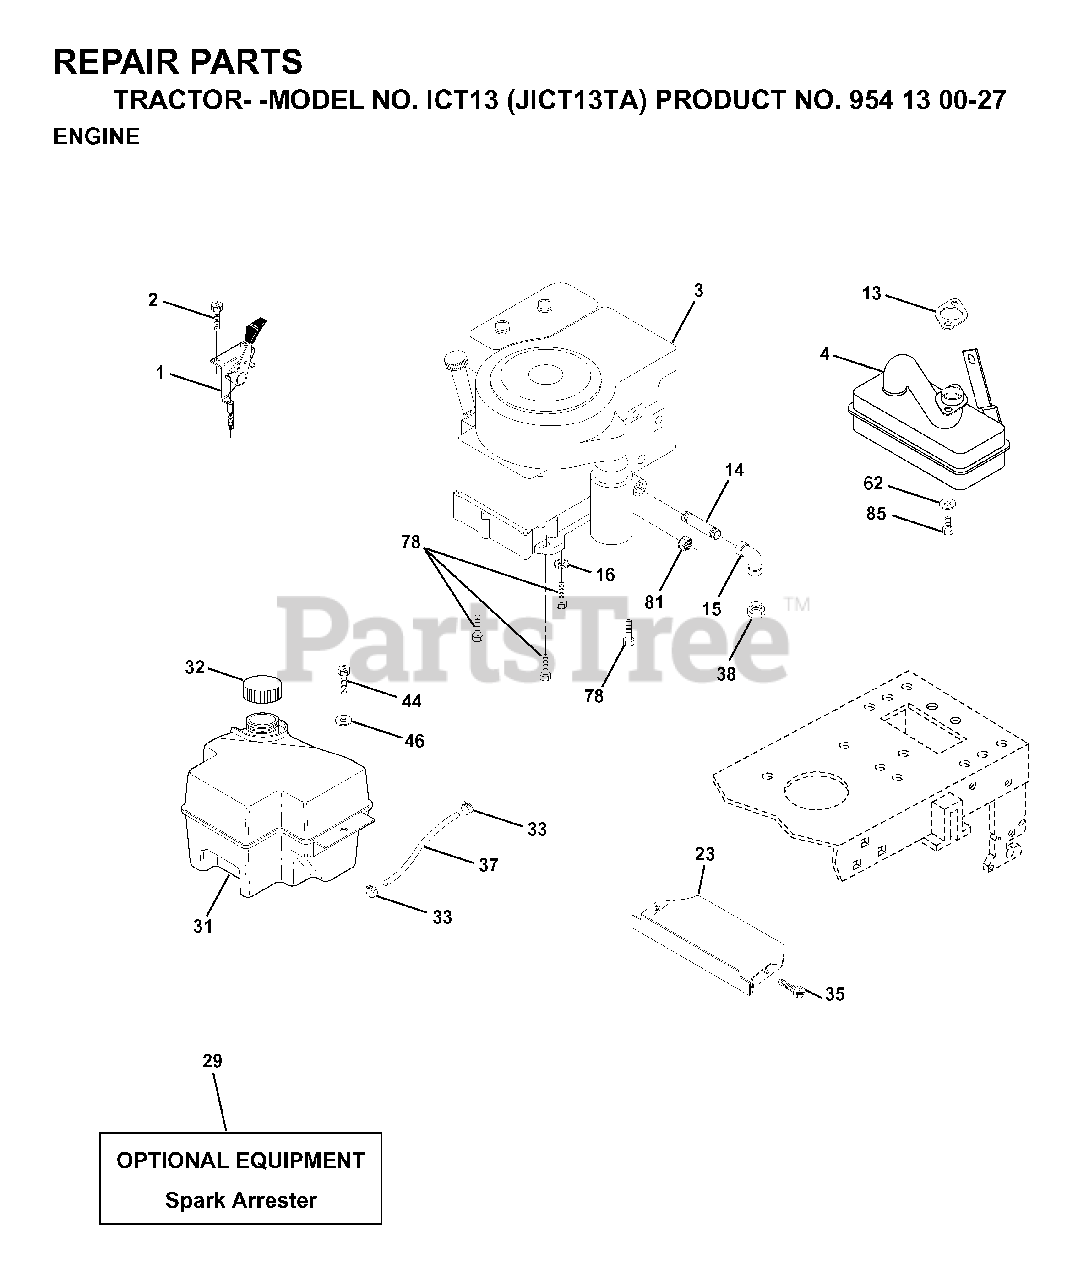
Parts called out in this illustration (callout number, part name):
2	SCREW LT
13	REPL BY 532 27 22-93
14	PIPE NIPPLE LT
15	ELBOW
16	LOCKWASHER
23	PROTECTOR
29	ARRESTER SPARK (OPTIONAL)
31	FUEL TANK
32	FUEL CAP
33	HOSE CLAMP
35	SCREW
37	LINE.FUEL.20
44	SCREW HEX CRT
62	LOCKWASHER
78	SCREW
81	NUT FLANGE 1/4-20 STARTER NUT
